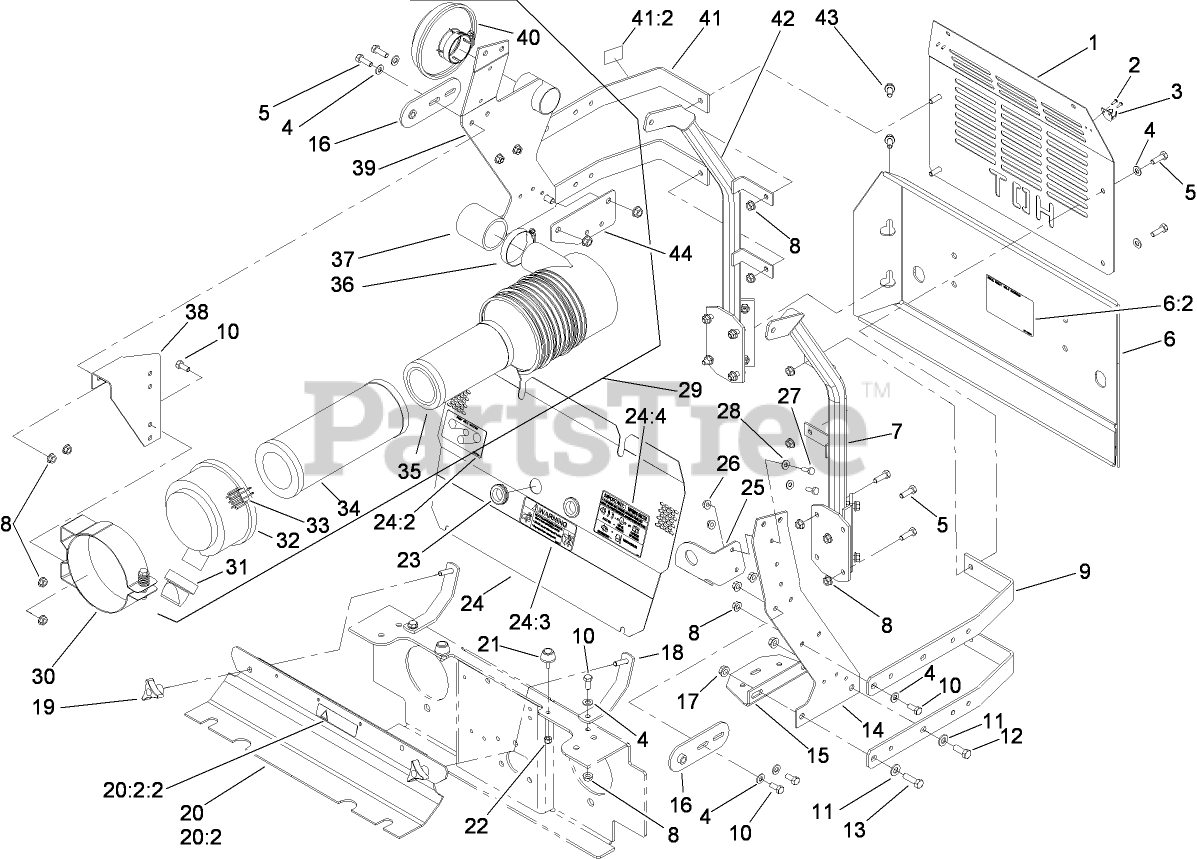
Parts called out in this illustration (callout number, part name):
1	GUARD-MUFFLER
2	RIVET
3	KEEPER-LATCH, RUBBER
4	WASHER-PLAIN
5	SCREW-HH
6	REAR BUMPER ASM
6:2	DECAL-BELT ROUTING, DECK DRIVE
7	FRAME-UPPER, LH REAR
8	NUT-HF
9	BAR-MOUNT FRAME, RADIATOR
10	SCREW-HH
11	WASHER-FLAT
12	SCREW-HH
13	SCREW-HH
14	MOUNT-SIDE, LH
15	BRACKET-BOTTLE
16	SHACKLE-HINGE
17	NUT-HHF, WHIZ
18	MOUNT-BELT SHIELD, ENGINE
19	KNOB-3 PRONG
20	ENGINE BELT SHIELD ASM
20:2	STRIP-SHIELD, BELT
20:2:2	DECAL-COVER, MISSING
21	BUMPER-RUBBER
22	NUT-LOCK, NI
23	GROMMET-RUBBER
24	ENGINE ACCESS PANEL ASM
24:2	DECAL-BELT ROUTING, PUMP
24:3	DECAL-BUZZER, WARNING
24:4	DECAL-DEVICES, ROTATING
25	BRACKET-BUZZER
26	NUT-HF
27	SCREW-HH
28	WASHER-FLAT
29	FILTER-AIR
30	BRACKET-FILTER, AIR
31	VALVE-VACUATOR
32	COVER-FILTER, AIR
33	LATCH-CLEANER, AIR
34	FILTER-AIR
35	FILTER-AIR, SAFETY
36	CLAMP-HOSE
37	HOSE-INTAKE
38	MOUNT-CLEANER, AIR
39	RH RADIATOR AND AC SUPPORT ASM
40	HOOD-CLEANER, 2" AIR INTAKE
41	BAR-RADIATOR
41:2	DECAL-SURFACE, HOT
42	FRAME-UPPER, RH REAR
43	SCREW-HHF
44	PLATE-FUEL FILTER MOUNT
